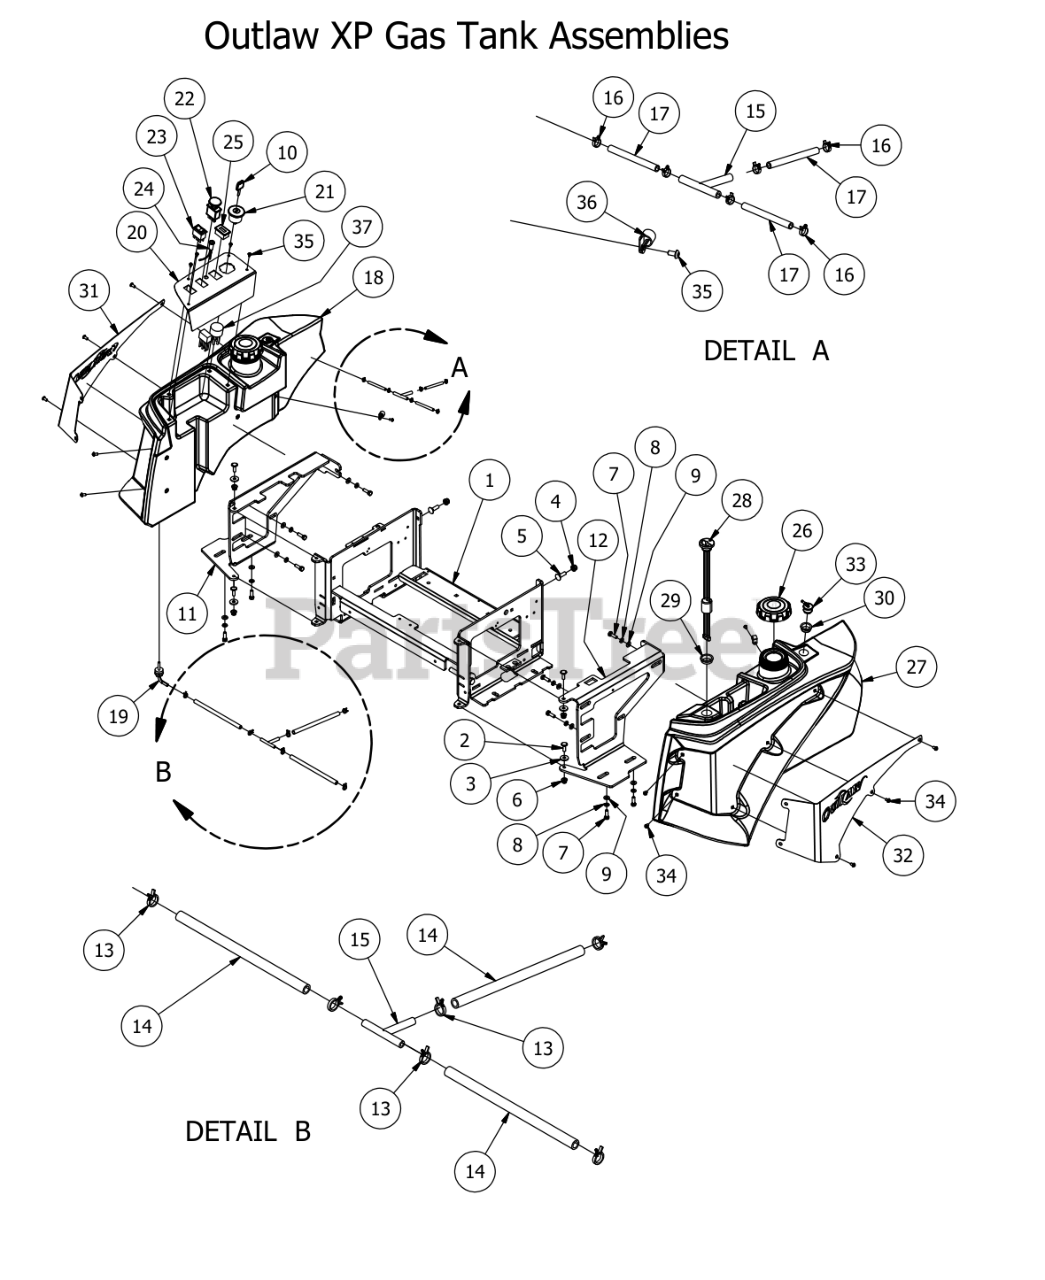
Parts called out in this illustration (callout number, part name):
1	2016 Outlaw Seat Bracket
2	5/16-18 x 1 Carriage Bolts Zinc
3	.360 ID Plastic Washer
4	3/8" Nylock Flange Nut
5	3/8" x 1 1/4" Carriage Bolt
6	5/16-18 Nylon Insert Flange Nut Zinc Orange Nylon
7	5/16" x 1" Bolt
8	5/16" Lock Washer
9	5/16" Flat Washer
10	Ignition Key
11	Outlaw 2015 Tank Support (Right)
12	Outlaw 2016 Tank Support (Left)
13	1/4 fuel clamp
14	1/4" fuel line hose
15	fuel line T
16	3/16 vinyl clamp
17	1/4" vinyl tubing
18	Outlaw 2015 Fuel Tank (Right)
19	Fuel Tank Hose Nipple w/Filter
20	Analog Control Panel Outlaw
21	Ignition Switch
22	PTO Switch
23	Rocker Deck Lift Switch
25	Tachometer
26	Fuel Cap (Kelch)
27	Outlaw 2015 Fuel Tank (Left)
28	Fuel Gauge w/Grommet
29	Grommet for Fuel Gauge
30	ROV Grommet
31	Outlaw Tank Panel (Right)
32	Outlaw Tank Panel (Left)
33	Rollover Valve - Black
34	1/4" x 1/2" BS C/S 18-8 SS
35	10-32 x 3/8" Button Socket Head Bolt
36	3/8 Cable Clamp-Black Nylon
37	Wiring Harness
